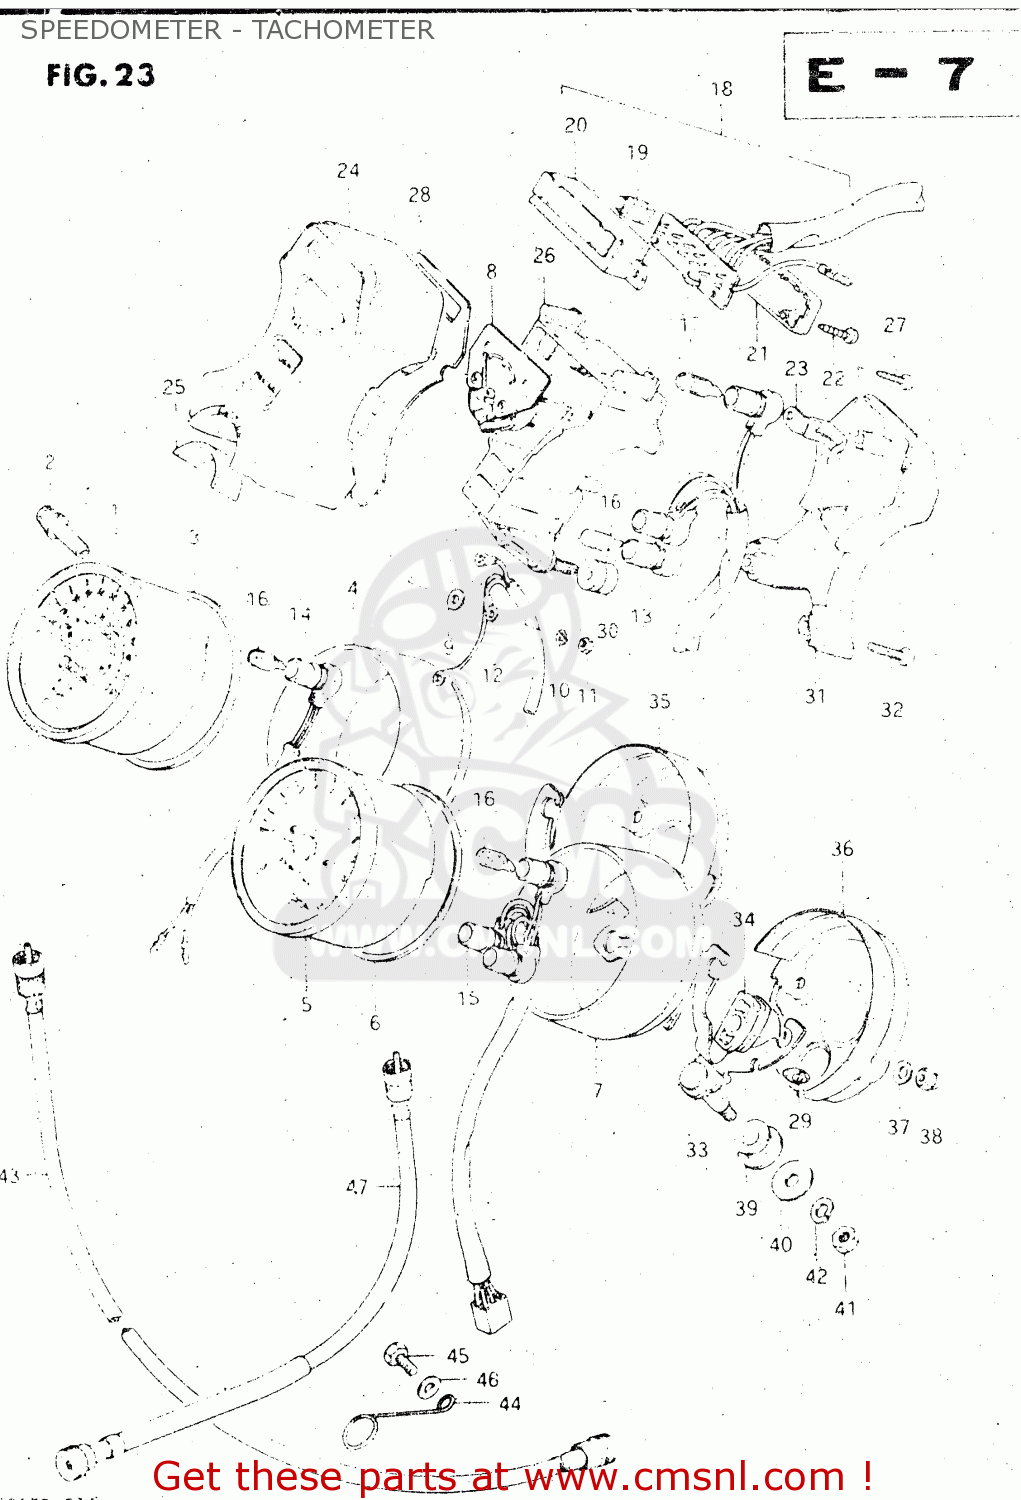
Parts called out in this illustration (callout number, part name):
1	METER.SPEEDO.KM
2	KNOB
3	CUSHION,SPEEDOMETER
4	COVER,SPEEDOMETER
5	TACHOMETER
6	CUSHION,SPEEDOMETER
7	COVER,TACHOMETER
8	METER,FUEL
9	WASHER,FUEL METER
10	LOCK WASHER
11	NUT 3MM
12	LEAD WIRE,FUEL METER
13	SOCKET,PILOT CASE
14	SOCKET,SPEEDOMETER
15	SOCKET,TACHOMETER
16	BULB(12V3.4W,T10)
17	BULB(12V1.7W,T10,WB121)
18	INDICATOR ASSEMBLY,GEAR POSITION
19	BULB(14V1.12W)
20	CASE,GEAR INDICATOR
21	COVER,LWR
22	SCREW,GEAR INDICATOR
23	CLAMP,CORD
24	CASE,PILOT BOX
25	SEAL,IGNITION SWITCH
26	CASE,PILOT BOX,INNER
27	SCREW,INDICATOR
28	PLATE,PILOT BOX
29	CUSHION
30	CUSHION,PILOT BOX
31	COVER,PILOT BOX,UNDER
32	SCREW
33	BRACKET,COMBINATION METER
34	CUSHION,METER
35	COVER,METER,UNDER
36	PLATE,TACHOMETER UNDER
37	WASHER
38	NUT
39	CUSHION,METER BRACKET
40	WASHER (8.5X29X1.6)
41	NUT
42	LOCK WASHER
43	CABLE ASSEMBLY,SPEEDOMETER
44	CLAMP,SPEEDOMETER CABLE
45	BOLT, UPPER
46	WASHER
47	CABLE ASSEMBLY,TACHOMETER
